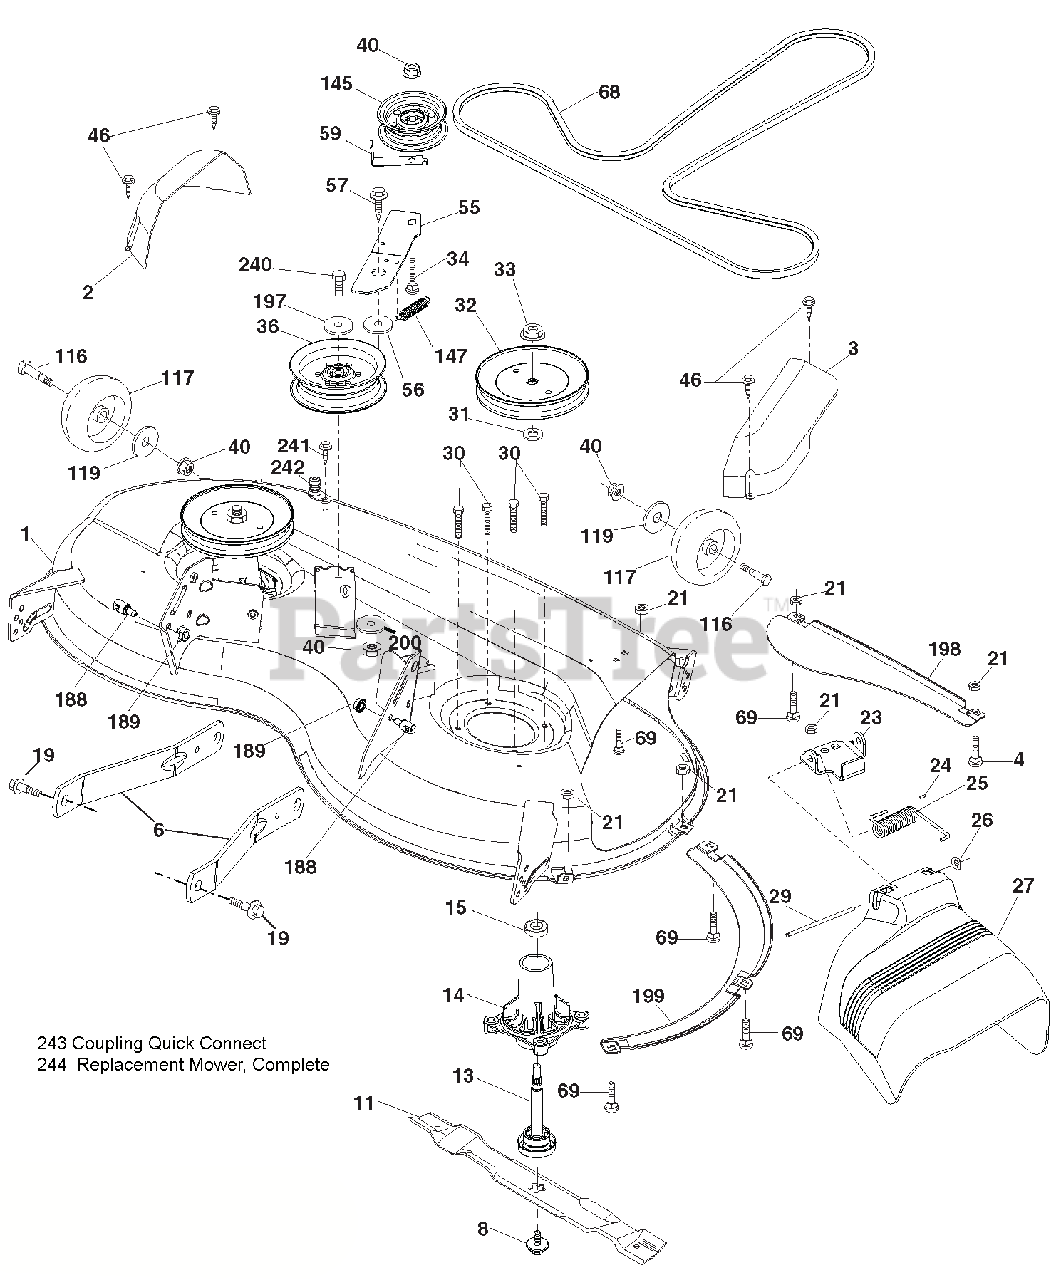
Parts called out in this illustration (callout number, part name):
1	MOWER HOUSING
2	COVER.MANDREL.LH.46"
3	COVER.MANDREL.RH.46"
4	BOLT.HEX.HD.1/4-20UNC X 3/4
6	ARM.SUSPENSION.MOWER.REAR.LD
8	BOLT/WASHER ASM.7/16-20.UNF
11	BLADE.MOWER.46"HI LIFT BAGGER
13	SHAFT ASM.MNDRL.N/GREASEABLE38
14	HOUSING.MANDREL.4PT.SERVICE
15	BEARING.BALL.MANDREL
19	BOLT.SHOULDER
21	Nut, Hex, Crownlock 5/16-18
23	BRACKET.DEFLECTOR.38/42"2005
24	CAP.SLEEVE..80X.112.BLK.MOWER
25	SPRING.TORSION.DFL.38/42/46.GR
26	NUT.PUSH.PHOS.& OIL
27	SHIELD.DEFLECTOR.MOWER 46"BLK
29	ROD.HINGE.42/46"
30	SCREW.THD ROLL.DOD PT.HEX
31	WASHER.SPACER.MANDREL
32	PULLEY.MANDREL.5.438 PD.42"
32	MANDREL ASM.SUB.N-GRS.4 BOLT
32	SHAFT ASSEMBLY, AND BEARING
32	ONLY - PULLEY/NUT/WASHER AND BLADE
32	BOLT/WASHERS NOT INCLUDED)
33	NUT.FLANGE.LOCK.TOP
34	BOLT.CARR.SH.3/8-16X1-1/2.GR5
36	PULLEY.IDLER.4.50.RAW
40	Nut, Hex, Flangelock 3/8-16
46	SCREW.THD.ROLL.1/4-20 X 5/8
55	IDLER.ARM
56	SPACER.RETAINER
57	SCREW.3/8-16X1.SMGML.TAP/R.BLK
59	GUARD.TUV.IDLER
68	V-BELT.DRIVE.MWR.MECHANICL.46"
69	BOLT.5/16-18HEX.WHS.HD.LCKSERR
116	BOLD SHLD "A" 2.41 "B" 1.66
117	WHEEL.GAGE.HALF.SPOKED
119	Washer 3/8 x 7/8 x 14 Ga.
145	PULLEY.IDLER 48"PRIMARY
188	STUD.FASTNER.W/'D'ANTI-ROTATIO
189	Nut, Lock Hex Flange 5/16-18 u
197	Washer 13/32 x 13/16 x 12 Ga.
198	BAFFLE.CENTER.FRONT
199	BAFFLE.FRONT.RH
200	WASHER.13/32 X 1 X 1/2.11GAHRD
240	BOLT.FIN.HEX.3/8-16X 2-1/4 GR5
242	PORT WASHOUT
